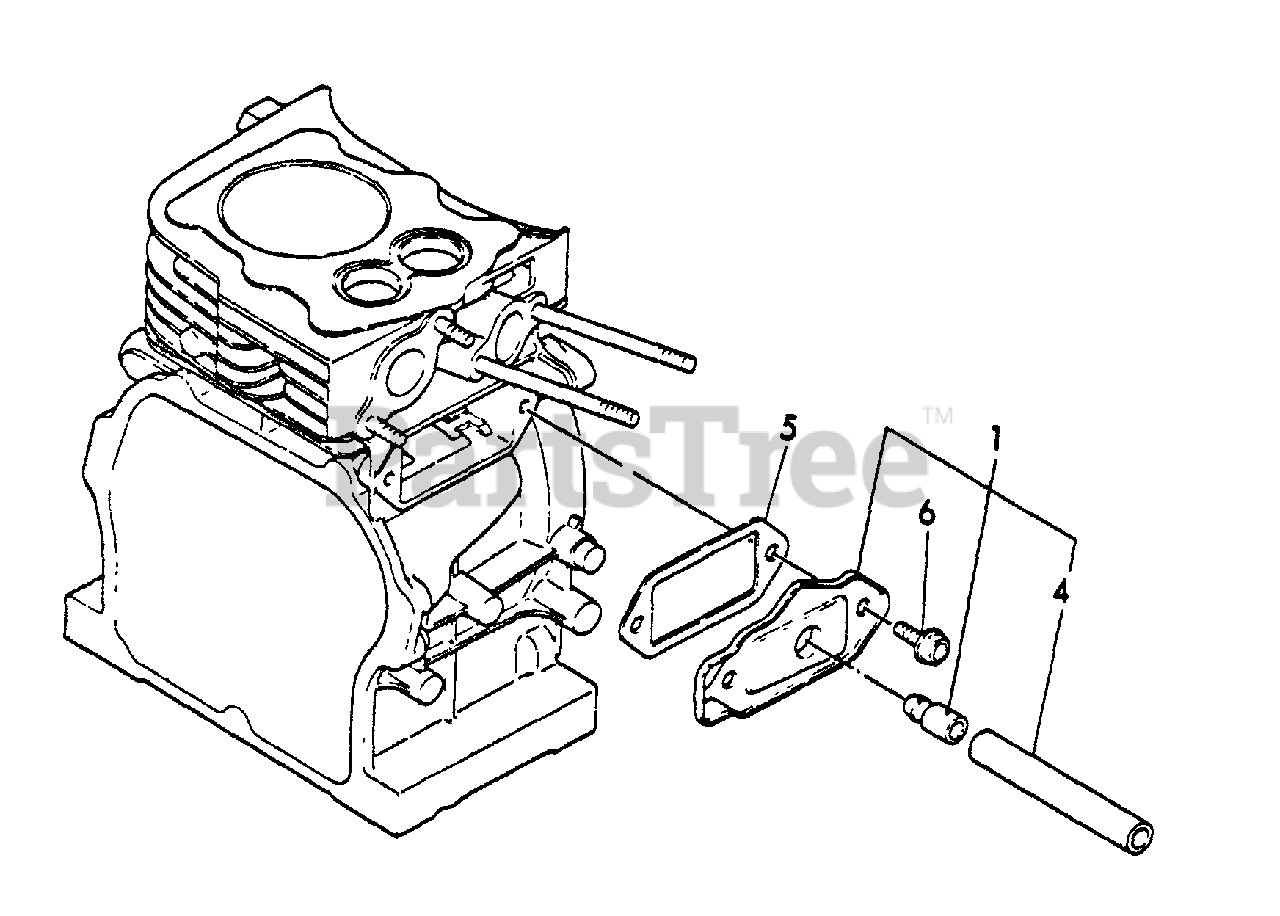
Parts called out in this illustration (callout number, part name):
1	VENT, FUEL TANK
4	PIPE - BREATHER
5	GASKET
6	BOLT - 6X8 -- PLATED
